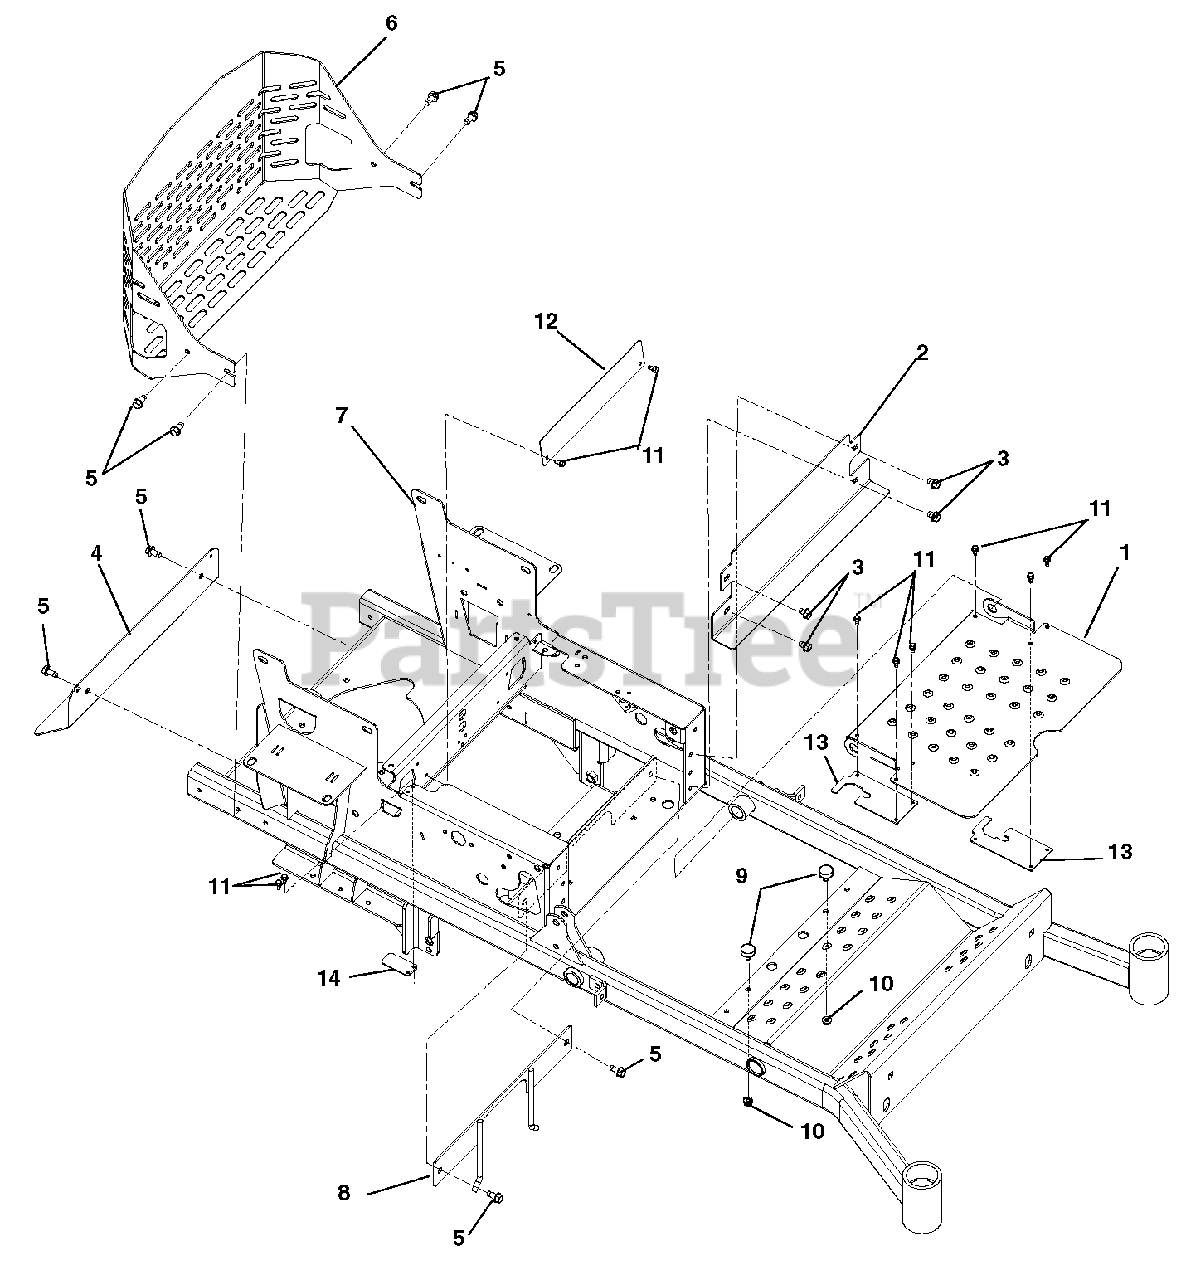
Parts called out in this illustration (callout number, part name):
1	Foot Plate
2	Kick Plate
3	Screw, Tapping .38-16 x .50 Hex Washer Head Thread Rolling
4	Muffler Heat Shield
5	Screw, Tapping .38-16 x .75 Hex Washer Head
6	Pro-Turn 100 Bumper
7	Pro-Turn 100 48" Main Frame Weldment
8	PTO Belt Finger Weldment
9	Bumper, Rubber
10	Nut, Spin Lock-Flange .312-18
11	Screw, Tapping .25-20 x .50 Hex Washer Head Thread
12	Fan Cover
13	Pro-Turn 100 CE Foot Plate Finger Cover
14	Finger Cover
